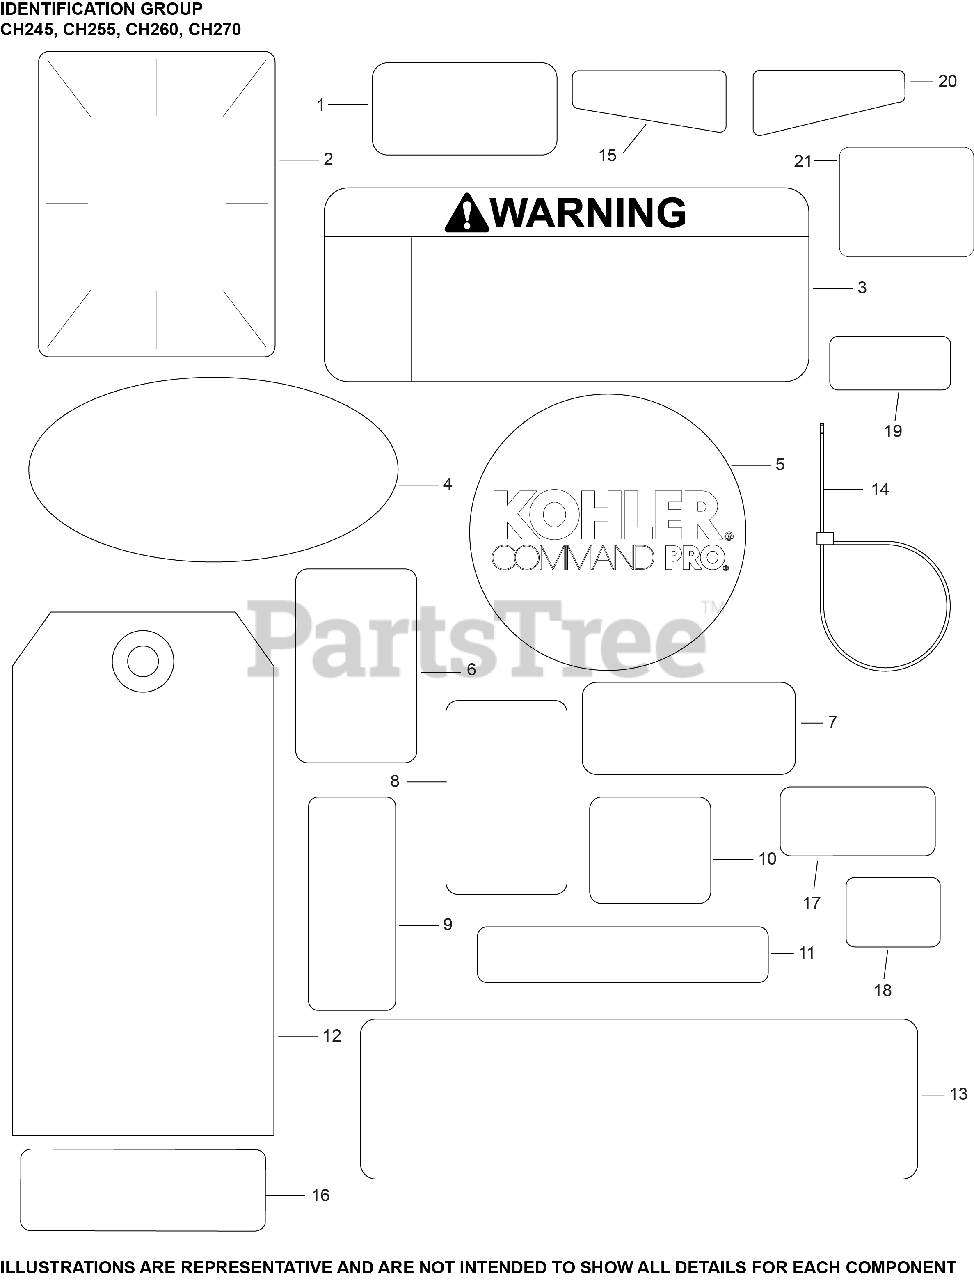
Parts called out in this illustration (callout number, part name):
1	LABEL, MAINTENANCE (CKY)
2	LABEL, CLEAR LAMINATION
3	DECAL, WARNING
4	DECAL, QUAD CLEAN
5	LABEL, RECOIL 75MM
7	LABEL, CANADIAN COMPLIANCE
9	DECAL, FUEL/CHOKE - ON/OFF
11	LABEL, THROTTLE
15	DECAL, 5.5HP/177CC CH255
17	DECAL, ETHANOL WARNING
18	DECAL, SUN
18	DECAL, SNOW
18	DECAL, ARROW
19	DECAL, ENGINE AND FUEL ON/OFF
